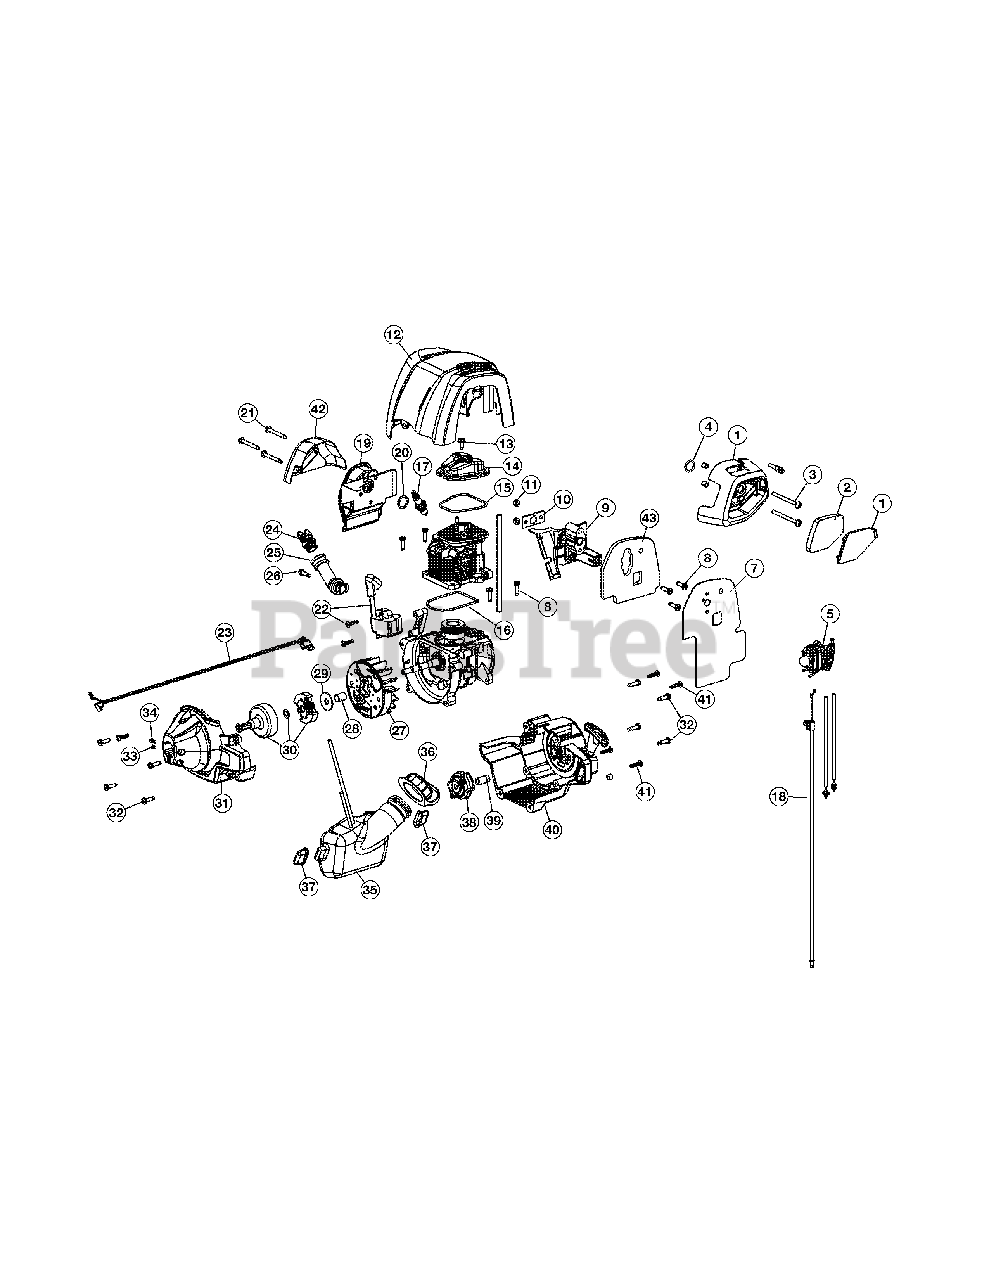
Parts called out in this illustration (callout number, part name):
1	Air Cleaner Assembly
2	Air Filter
4	Carburetor O-Ring
5	Carburetor Assembly
7	Carburetor Baffle
8	Screw
10	Insulator Gasket
12	Engine Cover
14	Valve Cover
15	Valve O-Ring
16	Cylinder O-Ring
17	Spark Plug
18	Throttle Cable
19	Muffler Assembly
20	Muffler Gasket
21	Muffler Bolt
22	Module Assembly
23	Lead Wires
24	Oil Plug Assembly
25	Oil Fill Tube Assembly
29	Clutch Washer
30	Clutch Assembly
31	Clutch Cover Assembly
33	Anti Rotation Screw
34	Clamp Screw & Nut
35	Fuel Tank
37	Fuel Tank Pad
38	Pawl Assembly
39	Electric Start Adapter
40	Starter Cover Assembly
42	Muffler Shield
43	Carburetor Heat Shield
